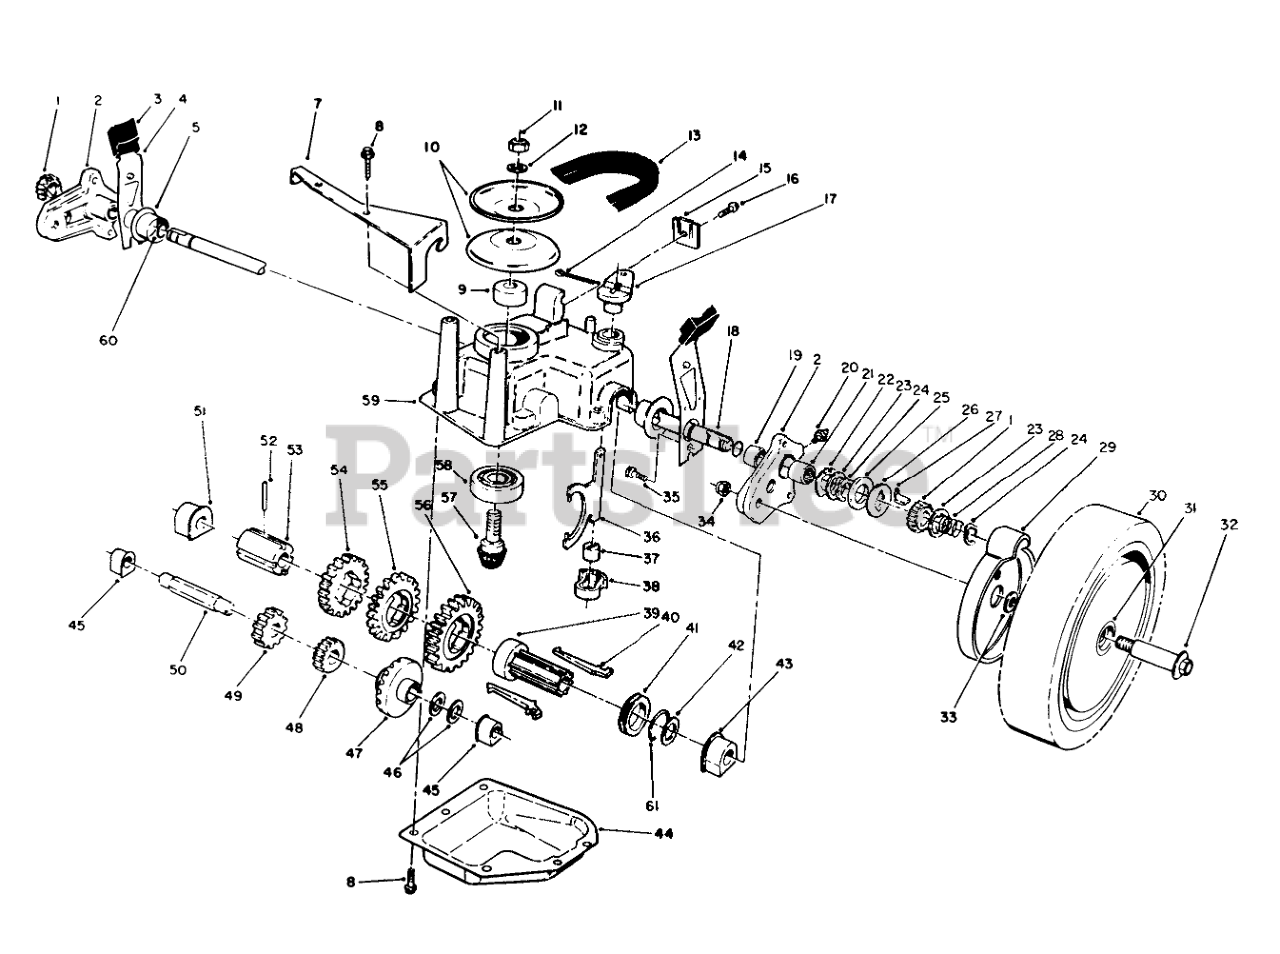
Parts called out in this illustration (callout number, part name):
1	GEAR-PINION
2	Pivot Arm Assembly (Incl. Ref. #19, 20, & 21)
3	KNOB-ARM
4	SPRING ARM ASM SP
5	CAP-END
7	Bracket-Guide
8	SCREW-HWHTF
9	SPACER
10	Pulley Half
11	NUT-HEX
12	WASHER-FLAT
13	V-BELT E
14	PIN-COTTER
15	Cable Clamp
16	SCREW-HWHTF
17	SHIFT LEVER
18	SHAFT-OUTPUT
19	BUSHING
20	FITTING-GREASE
21	BEARING-ROLLER
22	WASHER-ARM, PIVOT
23	WASHER-THRUST, KEYED
24	RING-CLIP, LOCKING
25	RING-FRICTION
26	WASHER-CLUTCH
27	KEY-ROCKING, LH
28	SPRING-COMPRESSION
29	COVER-WHEEL
30	Wheel-Tire & Gear Ass-y (Incl. Ref. #31)
31	BUSHING
32	WHEEL BOLT
33	SPACER-COVER, WHEEL
34	Nut
35	SCREW-HWH
36	YOKE-SHIFT
37	BUSHING-YOKE
38	RETAINER-FORK, SHIFT
39	SLEEVE-KEY, SHIFT
40	KEY-SHIFT
41	COLLAR-SHIFT
42	WASHER-PLAIN
43	BUSHING-OUTPUT
44	Cover-Gearcase
45	BUSHING
46	WASHER-THRUST
47	Gear-Bevel
48	PINION-20T
49	PINION-25T
50	SHAFT-INTERMEDIATE
51	BUSHING
52	PIN-SPRING
53	SLEEVE-GEAR
54	GEAR-39T
55	GEAR-44T
56	GEAR-49T
57	Gear-Pinion
58	BEARING-BALL
59	CASE-GEAR, UPPER
60	O-RING
61	CLIP-SPRING
